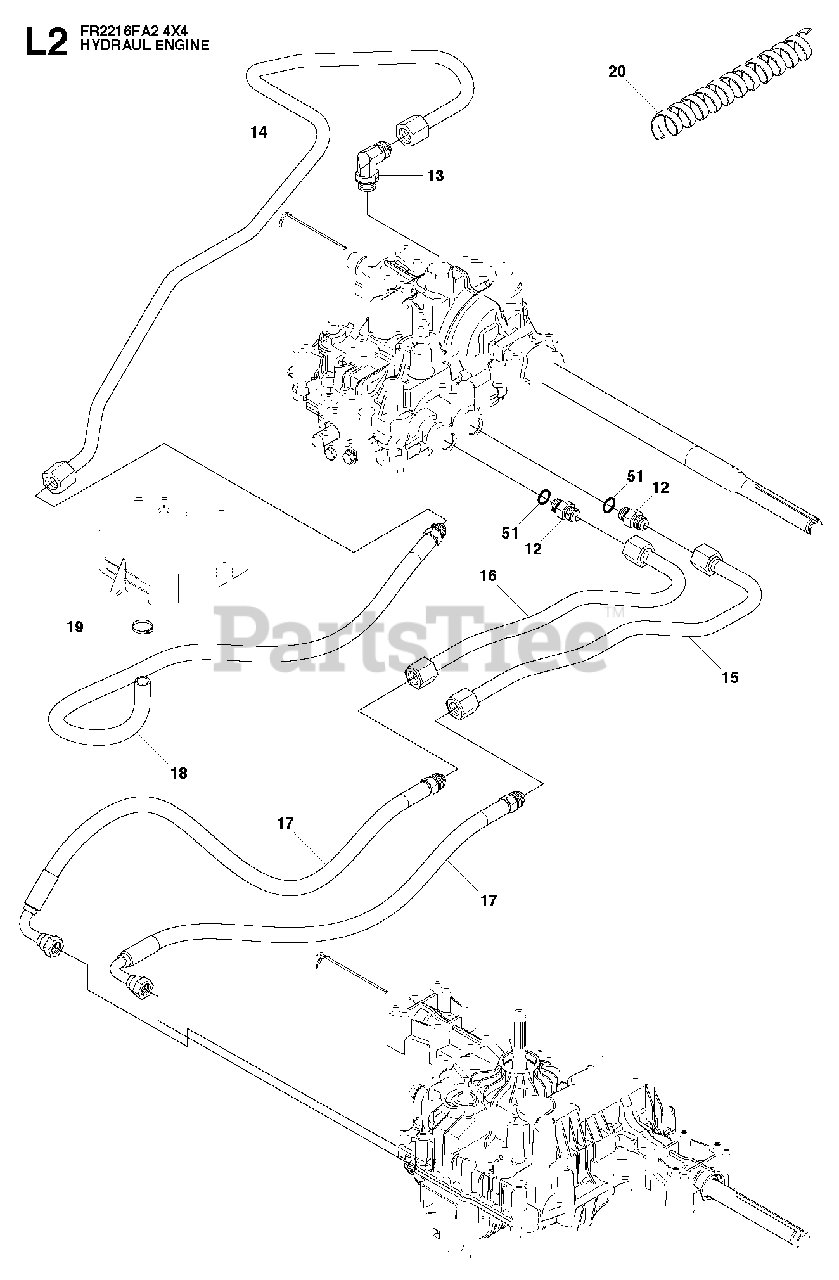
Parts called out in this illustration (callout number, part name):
12	PIPE FITTING
14	HYDRAULIC PIPE
15	HYDRAULIC PIPE
16	HYDRAULIC PIPE
17	HYDRAULIC HOSE
19	HOSE CLIP
20	PROTECTOR
